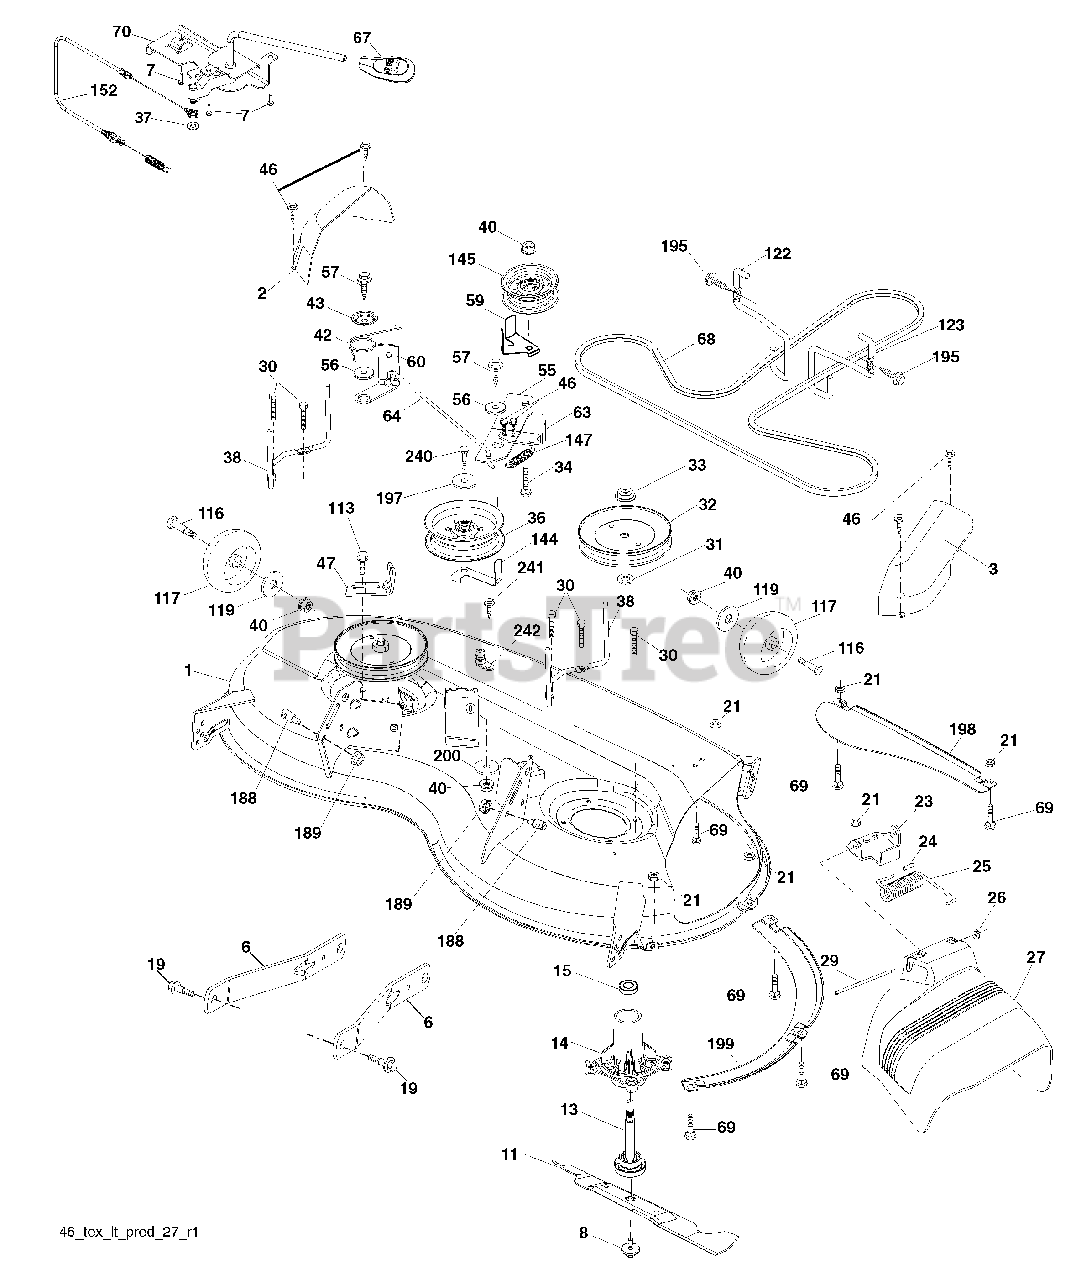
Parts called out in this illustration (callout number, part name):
1	Mower Housing
2	Cover Mandrel RH
3	Cover Mandrel LH
6	Arm Suspension
7	Screw #10 x 0.750 BOS Thread
8	Bolt/Washer asm 7/16-20 unf
11	Blade Mower
13	Shaft Assembly, Mandrel
14	Housing, Mandrel
15	Bearing, Ball, Mandrel
19	Bolt, Shoulder
21	Nut
23	Bracket, Deflector
24	Cap, Sleeve
25	Spring, Torsion, Deflector
27	Shield, Deflector
29	Rod, Hinge
30	Screw Thdrol Rolling Wsh Hd
31	Washer, Spacer
32	Pulley, Mandrel
33	Nut, Toplock, Flanged
34	Bolt Carr Sh. 3/8-16 x 1-1/2 Gr.
36	Pulley, Idler, 4.50 RAW
37	Washer 13/32 x 13/16 x 16 Ga.
38	Keeper Belt Mandrel
40	Nut, Lock Flg. 3/8-16 unc
42	Spring Trosion Brake
43	Spring Torsion Retainer
47	Bracket Clutch Cable
55	Arm, Idler
56	Spacer, Retainer
57	Screw Hexwsh Thd 3/8-16 x 1
59	Guard, Tuv Idler (94)
60	Arm Brake Mower LH
63	Arm Brake Mower
64	Linkage Brake
67	Handle, Clutch Cable
68	V-Belt
69	Bolt
70	Clutch Asm. Cable
113	Screw 5/16-18
116	Bolt, Shoulder
117	Wheel, Gauge
119	Washer 13/32 x 1-1/4 x 12 Ga.
122	Keeper Belt Eng. LH
123	Keeper Belt Eng. RH
144	Keeper Belt
145	Pulley Idler
147	Spring Return
152	Cable Clutch Manual w/Spr.
188	Stud Fastener
189	Nut Lock Hex Flange
195	Screw 3/8-16 x 3/4
197	Washer 13/32 x 13/16 x 12 Ga.
198	Baffle Center Front
199	Baffle Front RH
200	Washer 13/32 x 1 x 1/2 Ga.
240	Bolt 3/8-16 unc x 2-1/4 Gr. 5
241	Screw TT #10-32.5 3/8 Flg.
242	Port Washout
